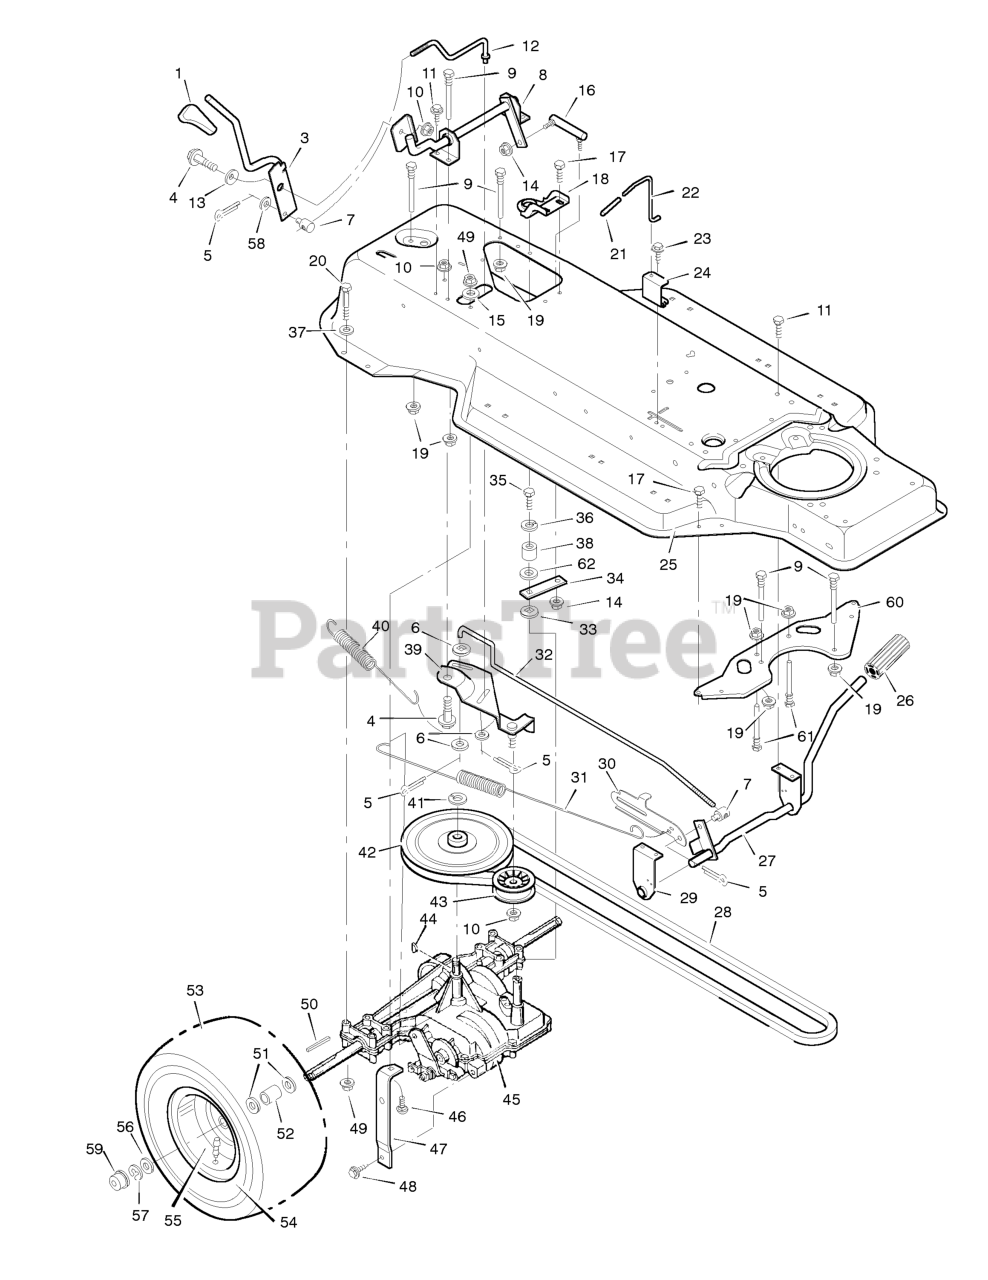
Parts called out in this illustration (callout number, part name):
1	Grip
3	Handle, Shift
4	Bolt, Shoulder
5	Pin, Cotter
6	Washer
7	Nut, Adjustable
8	Shifter Assembly
9	Guide, Belt
10	Locknut, Flange
12	Link, Clutch
13	Washer, Curved
14	Locknut, Flange
16	Link Assembly, Shifter
18	Bracket, Support
19	Nut, Flange
20	Bolt, Hex
22	Rod, Control
24	Guide, Bracket
25	Frame Assembly
26	Pedal, Clutch/Brake
27	Lever Assembly
28	Belt, Motion Drive
29	Bracket, Lever Support
30	Latch, Park Brake
31	Spring, Brake Extension
32	Rod, Clutch
34	Yoke, Shift
35	Bolt, Hex
36	Lockwasher
37	Washer
38	Pilot, Support
39	Bracket Assembly, Idler
40	Spring, Motion Drive
41	Ring, Retainer
42	Pulley, Motion Drive
43	Pulley, Backside Idler
44	Key, Woodruff
45	Transaxle, Peerless **
46	Bolt, Carriage
47	Support, Transaxle
49	Locknut, Flange
50	Key, Square
52	Spacer, Transaxle
53	Tire *
54	Wheel and Tire Assembly
55	Valve Stem
58	Washer
59	Hub Cap
60	Plate, Belt Guide
61	Guide, Belt
